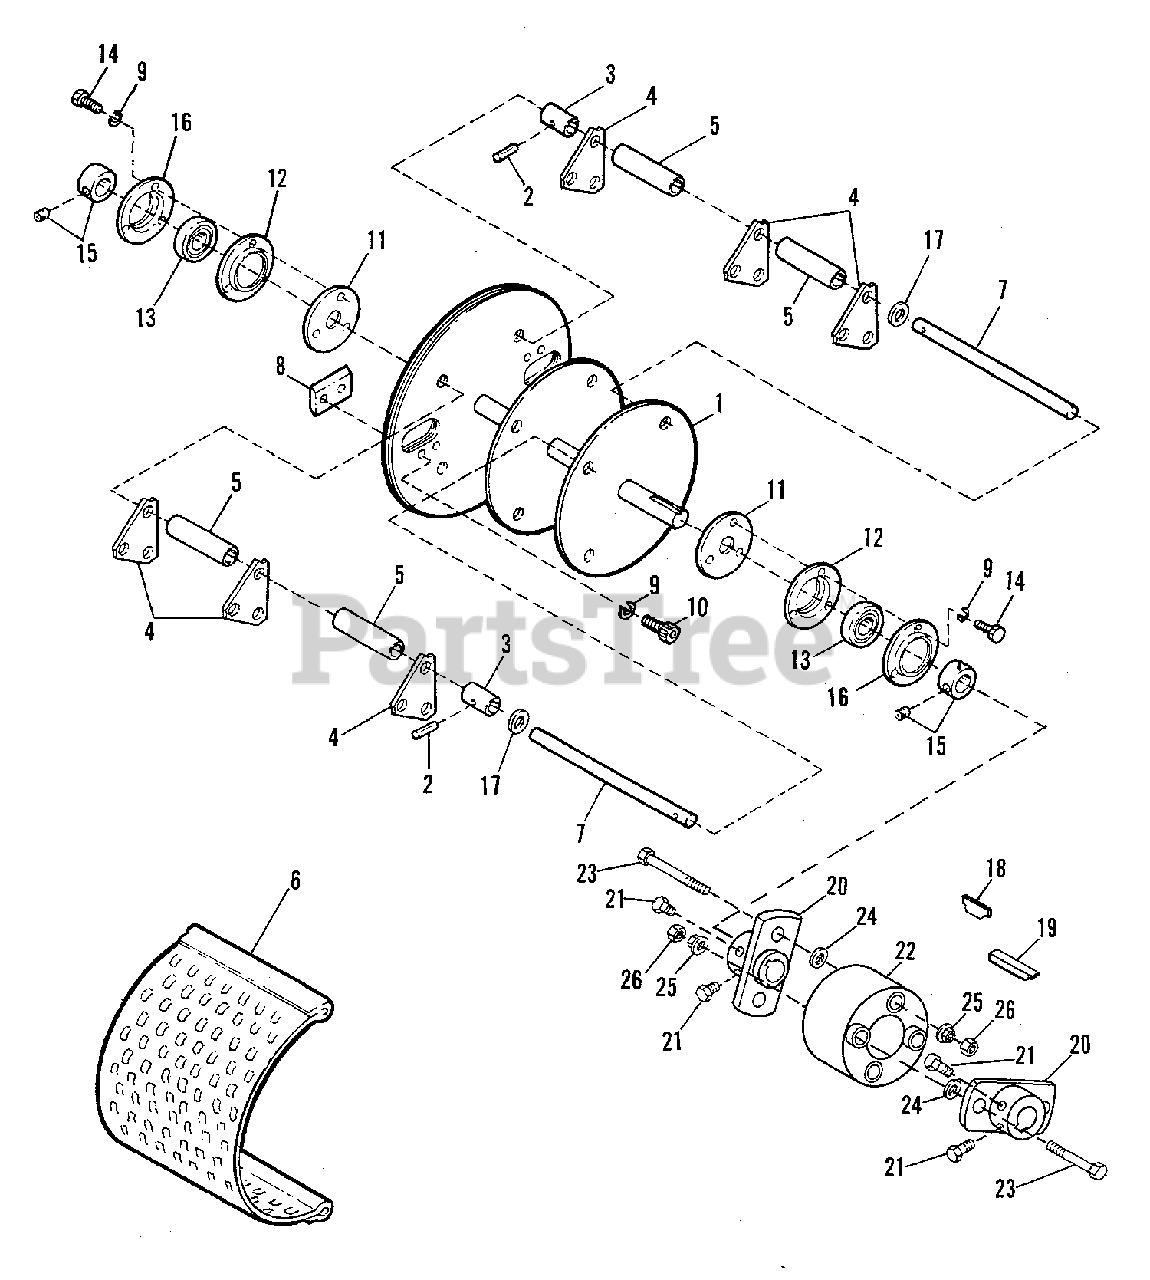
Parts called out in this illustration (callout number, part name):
2	ROLL PIN, 3/16 x 3/4
3	SPACER, Short
5	SPACER, Long
6	SCREEN, 3/4 Diameter Circle Openings (Standard)
6	SCREEN, 3/8 Diameter Circle Openings (Optional)
6	SCREEN, 1-1/2 Diameter Circle Openings (Optional)
6	SCREEN, 1-1/2 Oblong Slot Openings (Optional)
9	LOCKWASHER, 5/16
10	CAPSCREW, Socket Head, 5/16-24 x 7/8
11	GUARD, Bearing
12	FLANGETTE
14	CAPSCREW, Hex, 5/16-18 x 3/4
15	LOCKING COLLAR, Bearing
16	FLANGETTE, w/Zerk Fitting
17	WASHER, 1/2 ID x 7/8 OD x 1/16 Thick
18	KEY, Hi-Pro, 1/4 x 7/8
19	KEY, Hi-Pro, 1/4 x 1-3/8
20	HUB & PLATE ASSEMBLY, Drive
21	SETSCREW, Square Head Cup Point, 5/16-18 x 5/8 GR 8
22	COUPLER, Drive
23	CAPSCREW, Hex Head, 3/8-16 x 2-3/4 GR 8
24	WASHER, 13/32 x ID x 1 OD x 1/8 Thick
25	NUT, Hex Flange, Machine Lock, 3/8-16
26	LOCKNUT, Two-Way, 3/8-16
